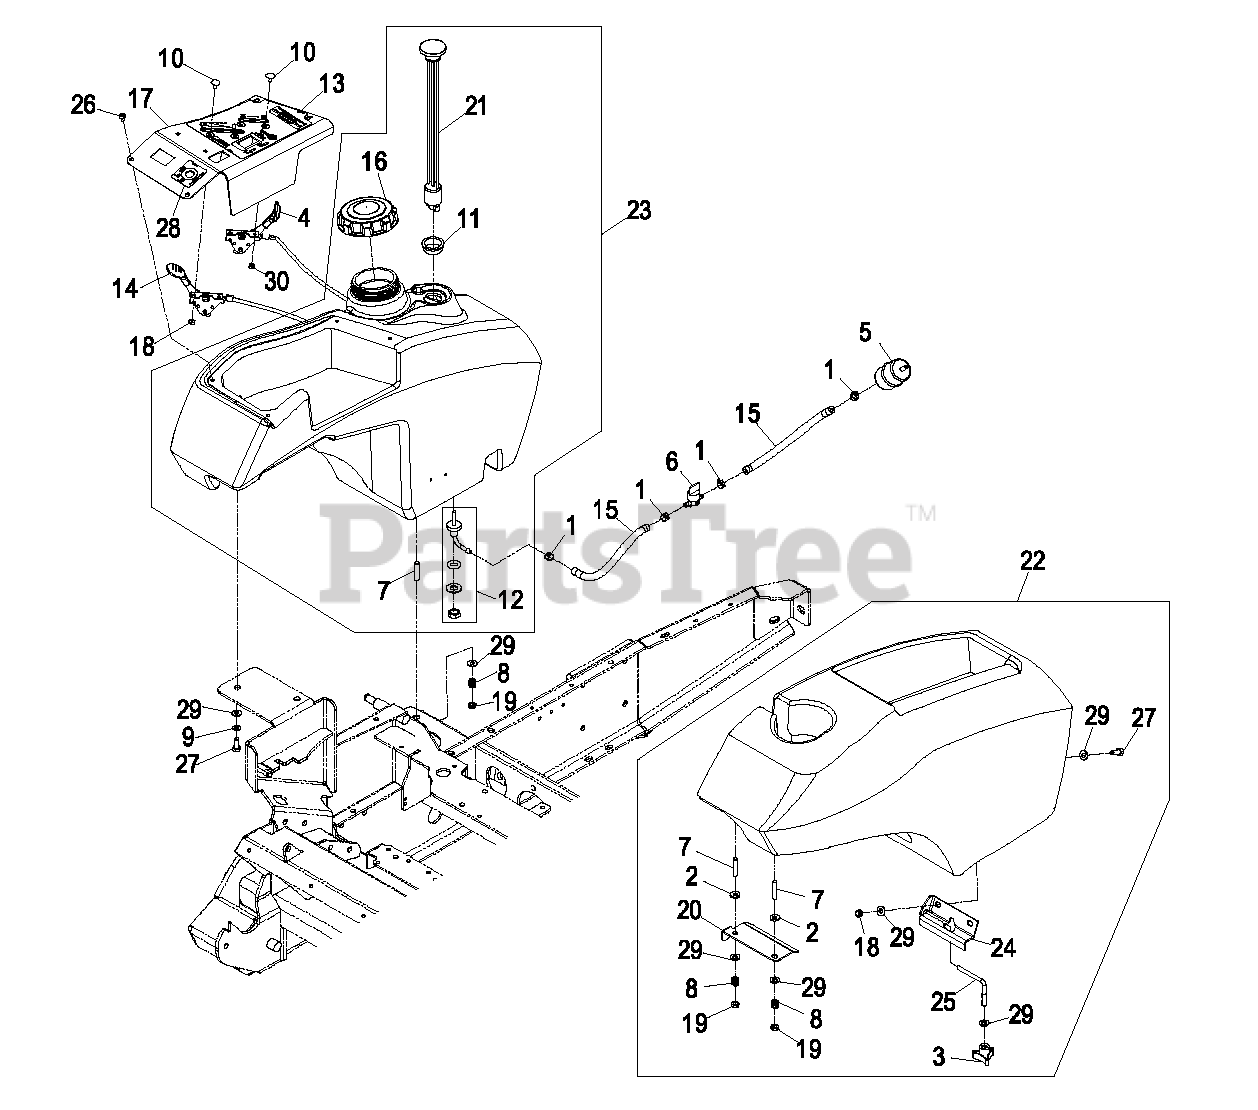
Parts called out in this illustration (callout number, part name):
2	WASHER-SPRING
3	KNOB-3 PRONG
4	CONTROL,CHOKE
5	Kohler Part No. 2405010 Fuel Filter
5	Briggs Part No. 695327 Fuel Filter
6	VALVE-FUEL
7	STUD
8	SPRING-TANK, FUEL
9	WASHER-LOCK
10	BOLT-CARR
11	CONTACT ORDER SERVICES
12	FITTING-FUEL, BULKHEAD
12	O-RING,BULKHEAD FITTING
13	DECAL,CONTROL FMZ A/C
14	CONTROL,THROTTLE
15	HOSE-FUEL
16	CAP-FUEL, GAS
17	ASM,CONTROL PANEL FMZ A/C
18	NUT-LOCK, NI
19	NUT-LOCK, NI
20	HOOK,FENDER (PLATED)
21	Gauge, Fuel
22	ASM,FENDER FMZ
24	BRACKET,FENDER
25	BOLT,FENDER
26	SCREW-PPH
27	SCREW-HH
28	DECAL,IGNITION
29	WASHER-PLAIN
